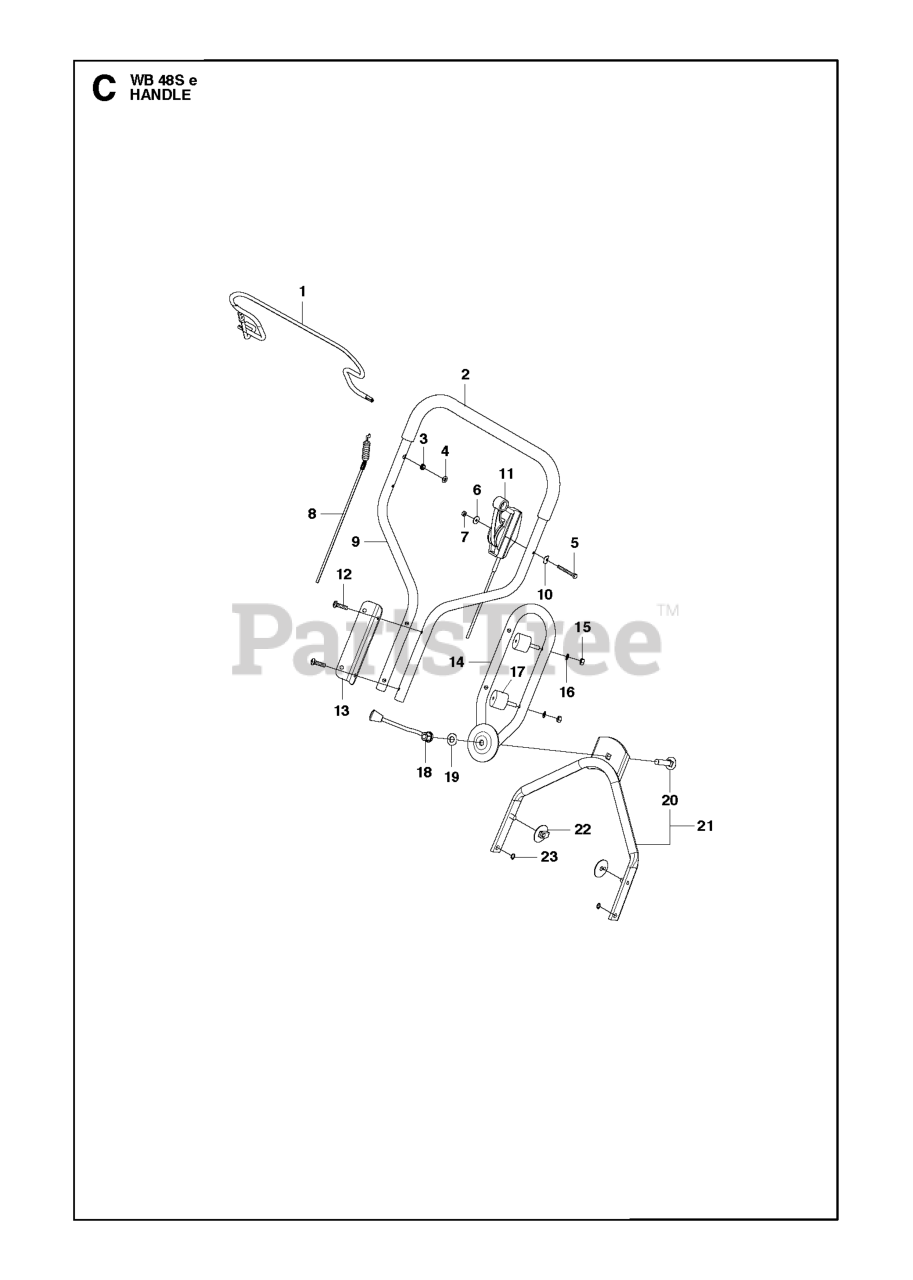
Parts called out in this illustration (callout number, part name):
5	SCREW M6X55
7	NUT FLANGE - M6
15	NUT
23	RETAINING RING SGA 10
